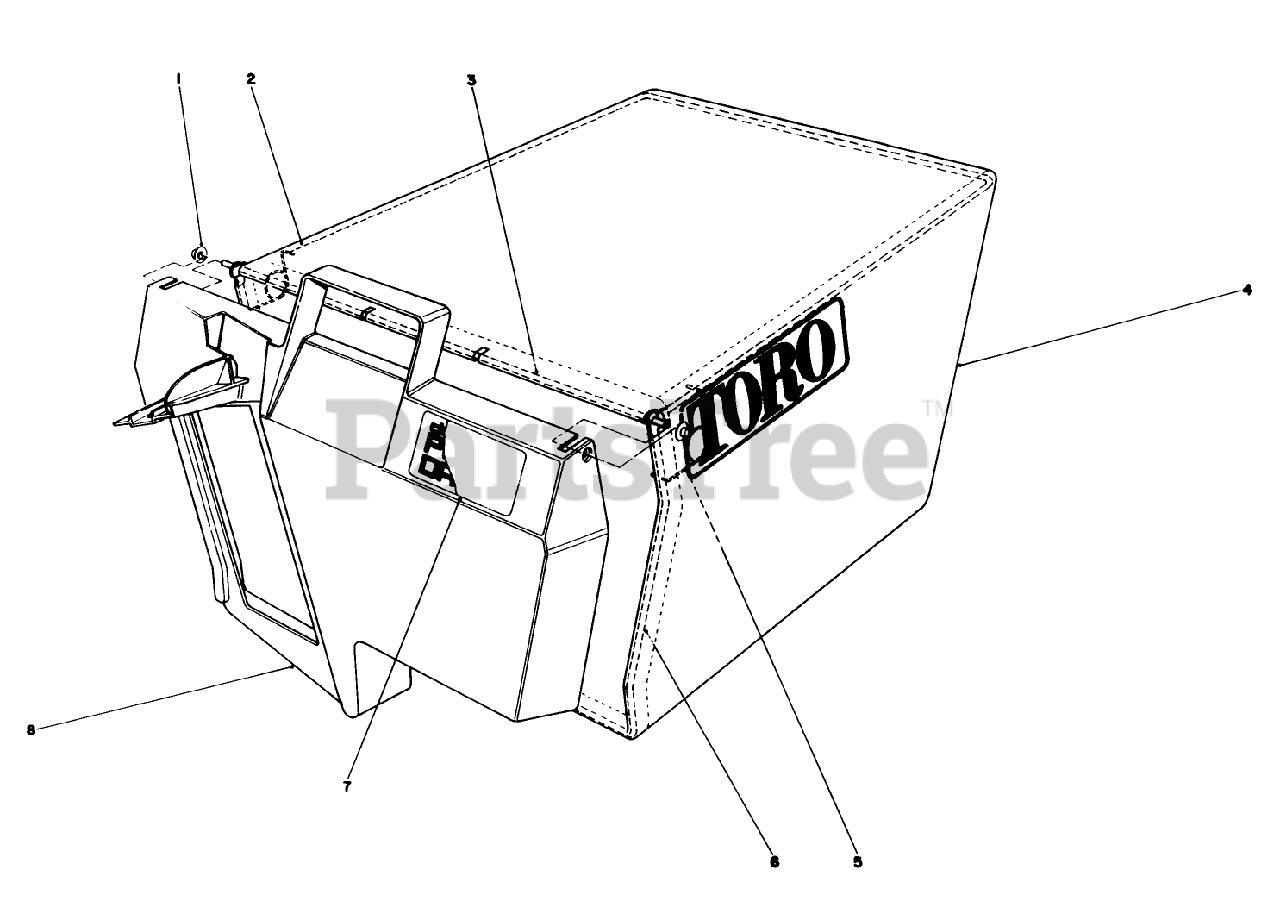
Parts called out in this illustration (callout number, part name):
1	NUT-PUSH
3	HINGE-DOOR, BAG
5	SPRING
6	FRAME-BAG
